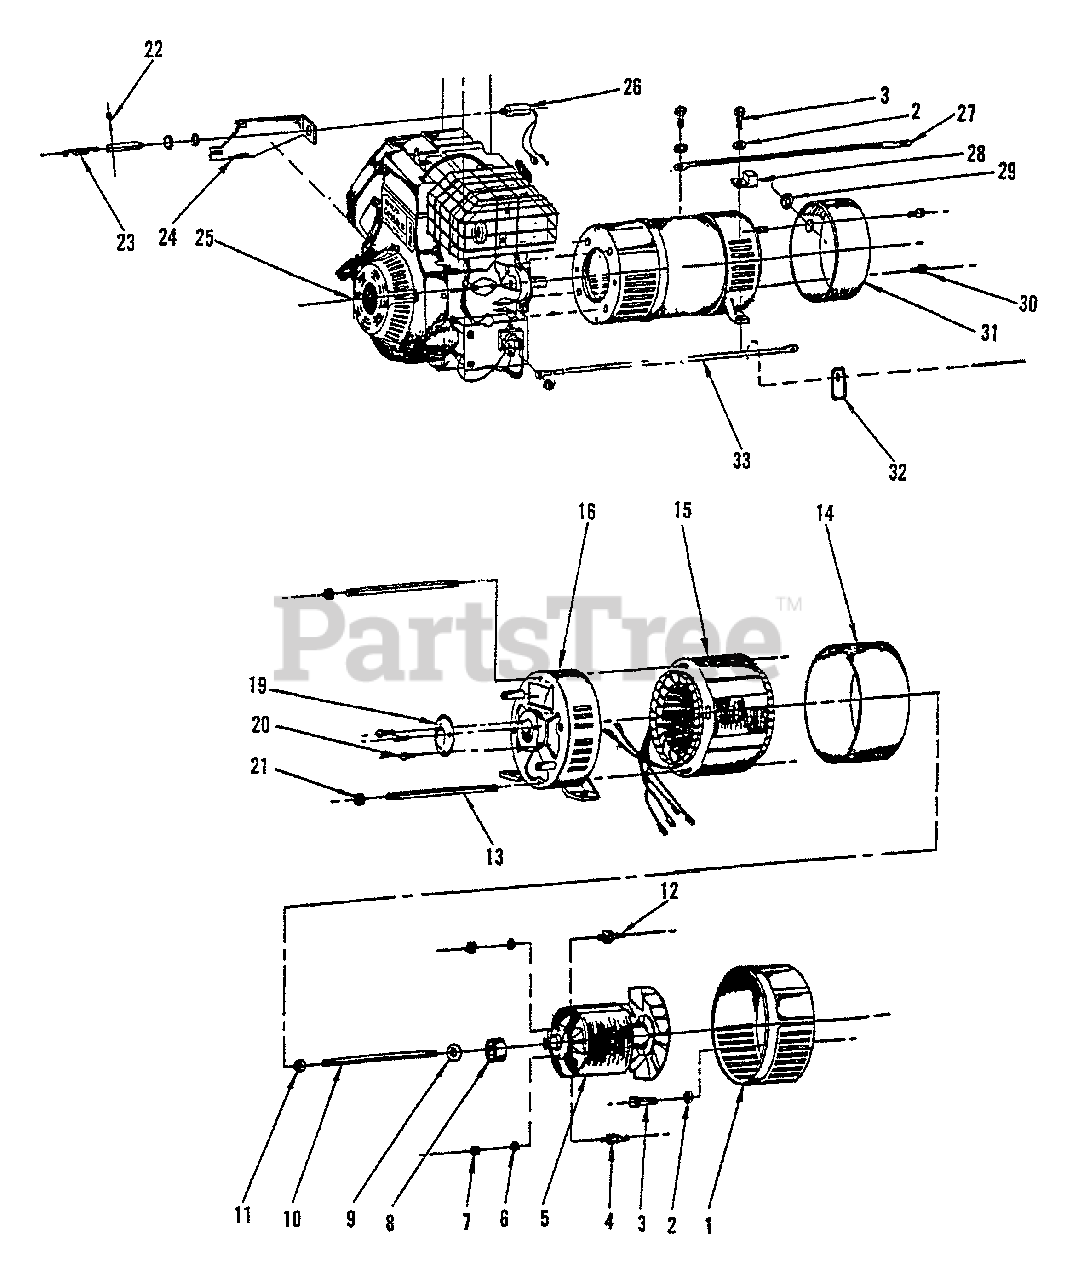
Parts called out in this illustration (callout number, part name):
1	DRIVE END ADAPTER CASTING
2	WASHER, LOCK 3×8
3	SCREW - 3/8-16×1.00" -- HEX HEAD CAP
4	DIODE
5	ROTOR ASSY
8	BEARING
9	LOCKWASHER - 5/16"
10	ROTOR THRU BOLT
11	NUT - 5/16-24 -- KEPS
12	DIODE
13	BOLT, STATOR
14	BAND, COVER
15	STATOR ASSY
16	CASTING, BEARING
19	COVER, BEARING
20	SCREW #10×24×1×2
21	NUT - 1/4-20 -- KEPS
22	PIN - COTTER
23	SPRING, ECHO-MIZER
24	BRACKET, SOLENOID
26	SOLENOID ASSY
27	CABLE, BATTERY - ( - )
28	LUG, GROUND - 1/0-14 CU/AL
29	GROMMET
30	SCREW - 10-24 -- SLOT HEAD
31	COVER, END
32	LABEL - POS. BATTERY (+)
33	CABLE, BATTERY - ( + )
